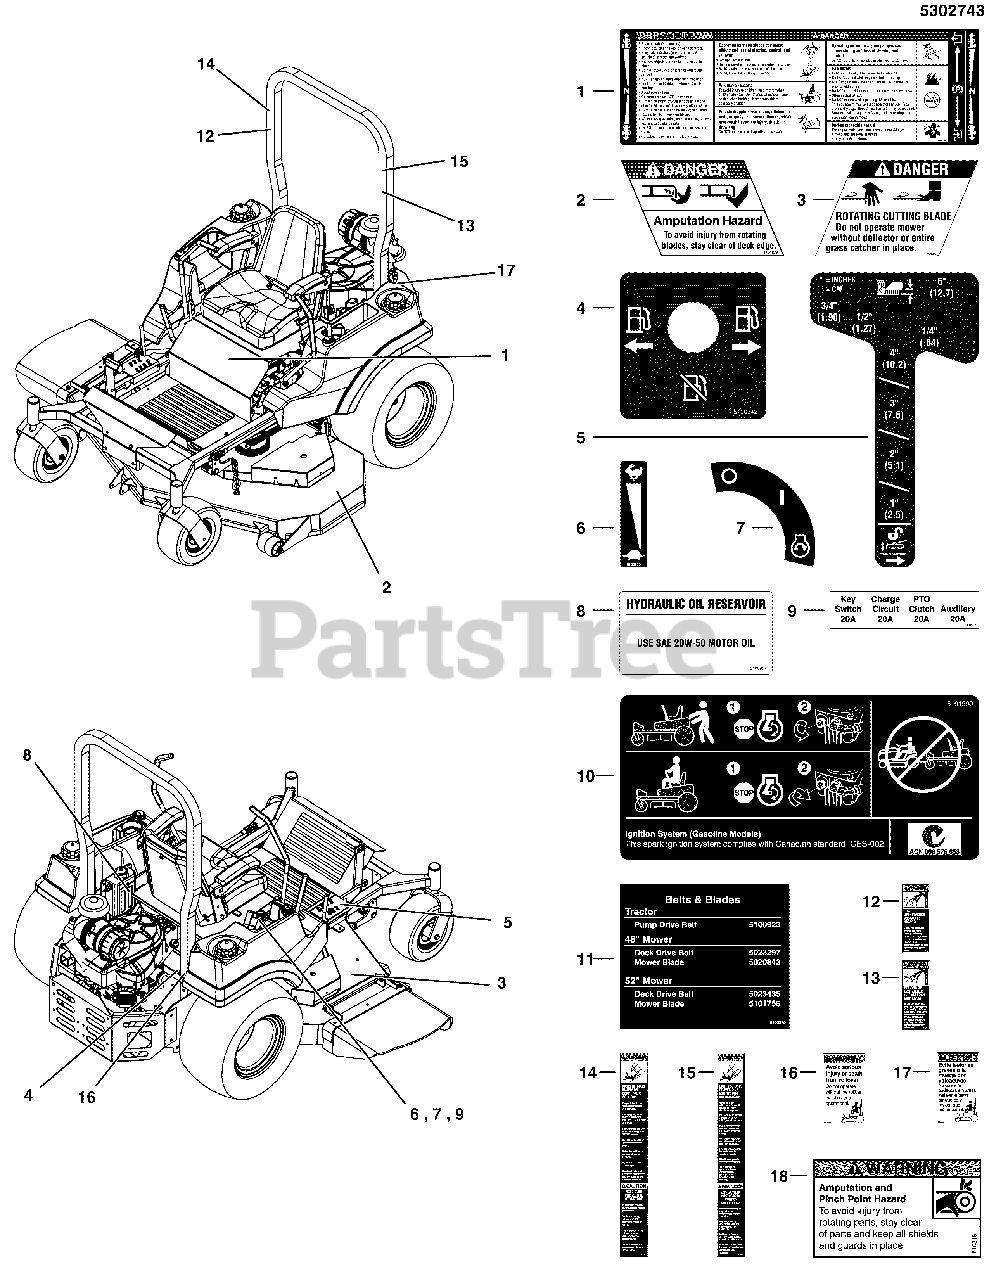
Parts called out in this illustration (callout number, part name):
1	DECAL, MAIN
2	DECAL-DANGER DO NOT PUT HAND/FEET IN MWR
3	DECAL-DANGER DO NOT OPERATE W/O DEFLECTR
4	DECAL, FUEL VALVE
5	DECAL-HEIGHT CITATION
6	DECAL, THROTTLE CONTROL
7	DECAL, IGNITION SWITCH
8	DECAL, HYDRAULIC OIL, SAE 20W50
9	DECAL, FUSE LOCATION
10	DECAL, TRANSAXLE RELEASE, S200XT
11	DECAL, BELT & BLADE, S150XiCD DECK
12	DECAL, WARNING, ROLL BAR (SV)
16	DECAL, WARNING, ROLL BAR
17	DECAL, WARNING, ROLL BAR, SP
18	WARNING, HAND IN BELT, ENG ONLY
